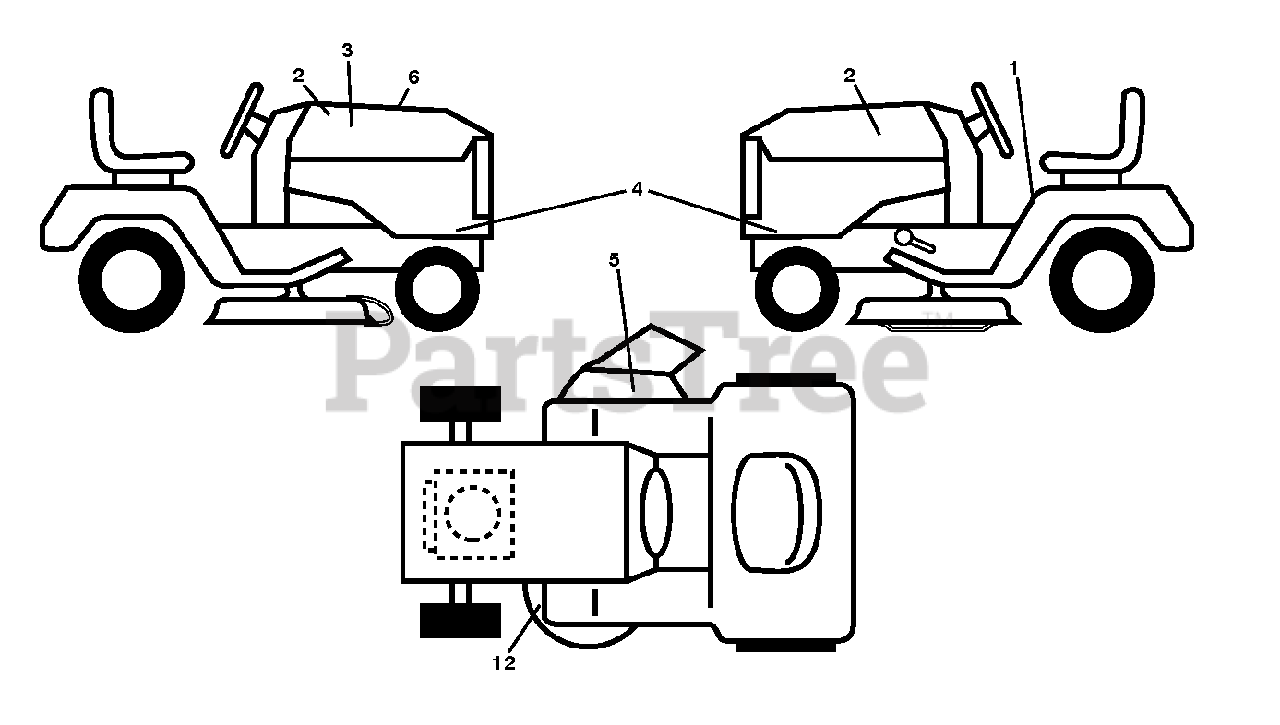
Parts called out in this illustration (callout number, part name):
1	DECAL.FENDER.WARNING.ENGLISH
2	DECAL.BADGE.170MM.TEXTLOGO.
3	Decal, Replacement LCC 452 TLW 38
4	Tractor Side Panel Decal
5	DECAL, DECK DEFLECTOR, WARNING
6	DECAL.WARNING.CUST.RESP.E85.
12	DECAL.DECK.SCH.36,38,94.NONCR
